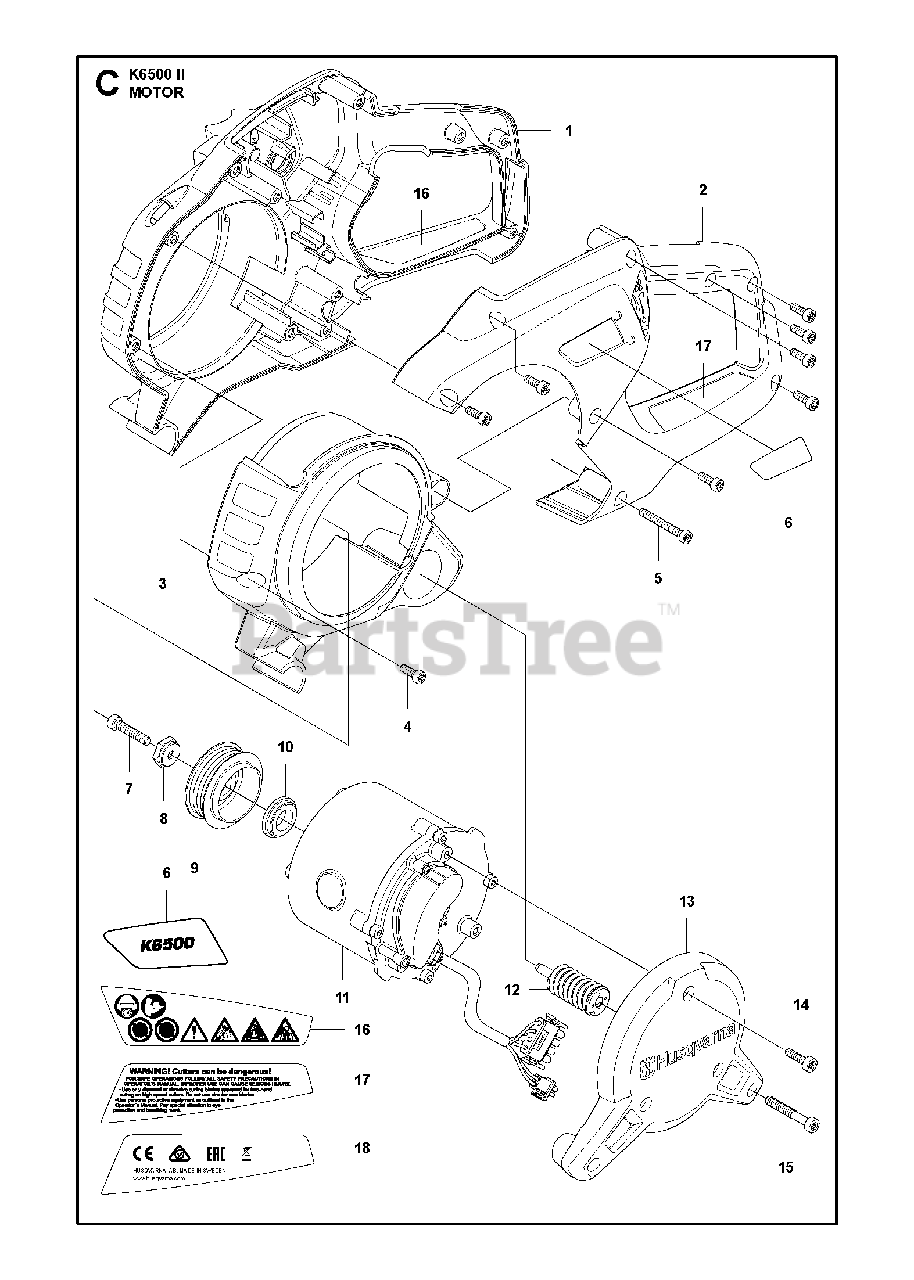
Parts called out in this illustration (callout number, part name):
4	SCREW ITXSCT
7	SCREW ITXSCM
9	DRIVING PULLEY
12	ANTIVIBRATION ELEMENT
14	SCREW ITXSCM
15	SCREW ITXSCM
